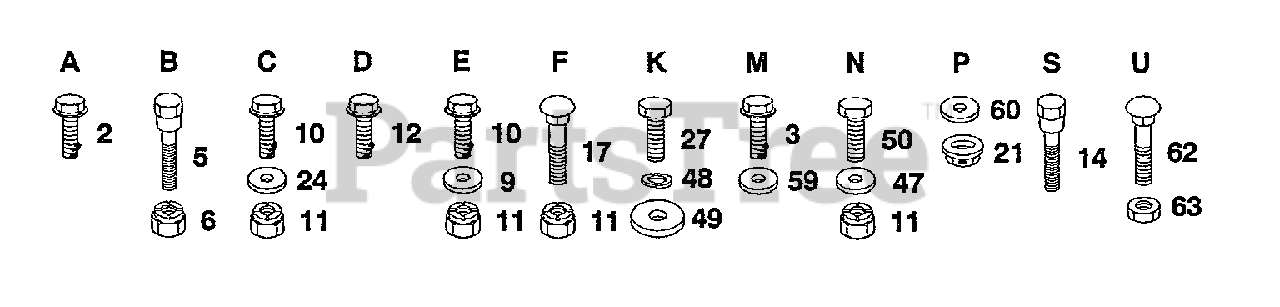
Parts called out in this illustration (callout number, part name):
2	SCREW
3	SCREW GTV
9	WASHER
12	SCREW LT
14	"BOLT,SHOULDER"
17	BOLT
21	PAL NUT LT
24	WASHER
27	BOLT
47	WASHER
48	LOCKWASHER
49	WASHER
50	BOLT
59	WASHER
60	WASHER PM
62	BOLT
